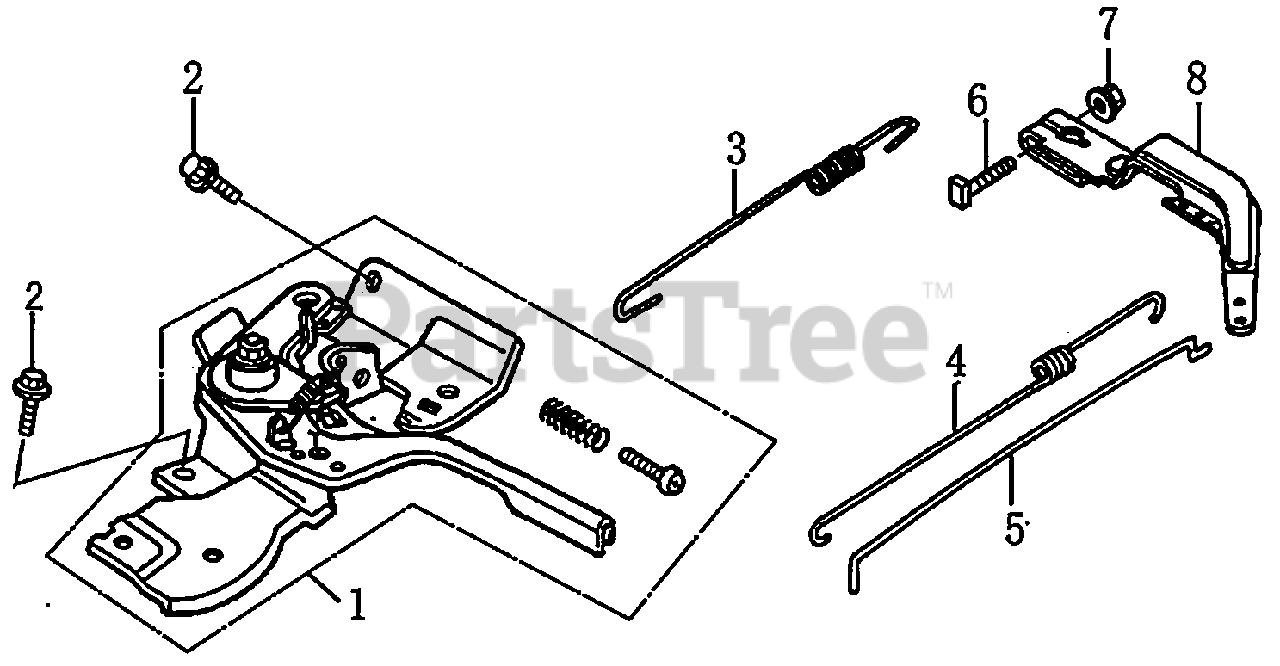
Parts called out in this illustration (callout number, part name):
1	CONTROL ASSY.
2	BOLT, FLANGE
3	SPRING, GOVERNOR
4	SPRING, THROTTLE RETURN
5	ROD, GOVERNOR
6	BOLT, GOVERNOR ARM M6×21
7	NUT, FLANGE
8	ARM, GOVERNOR
